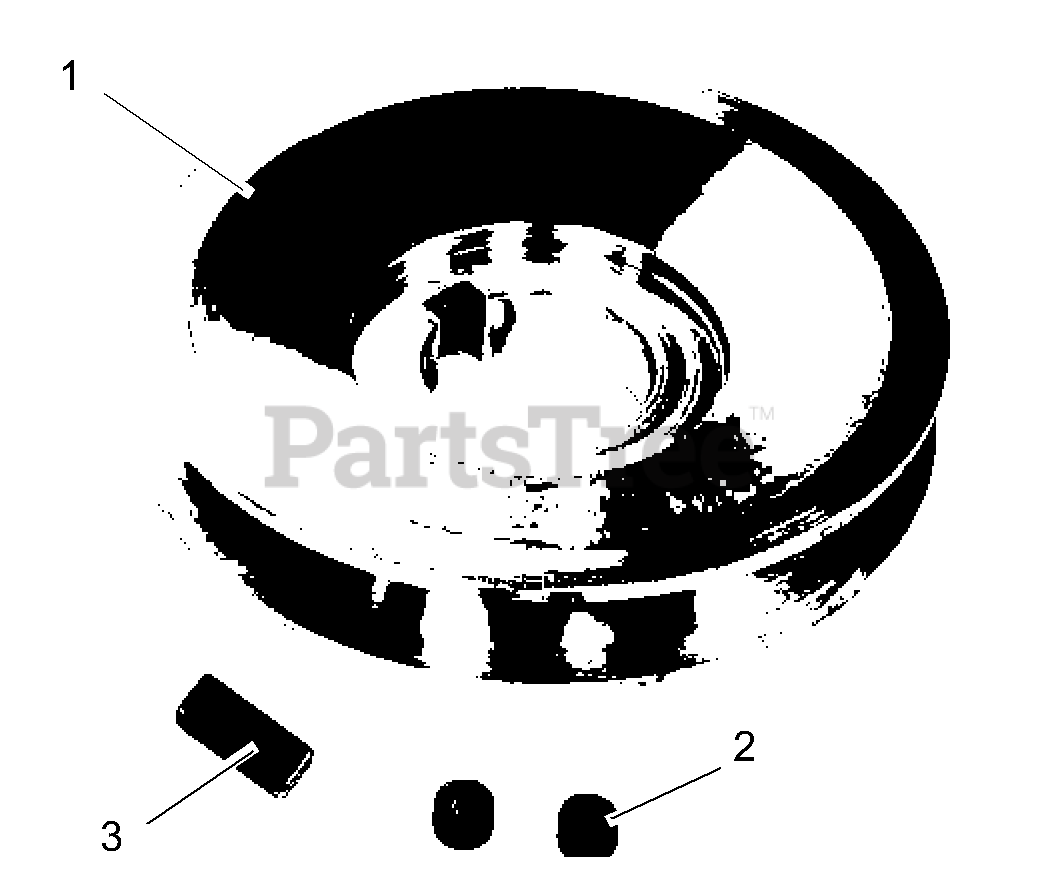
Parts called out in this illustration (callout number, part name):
1	PULLEY-DRIVEN, 3.50 DIA
2	SCR-SET .25-28X.25 SKHCUP OH
3	SHAFT,AXLE
